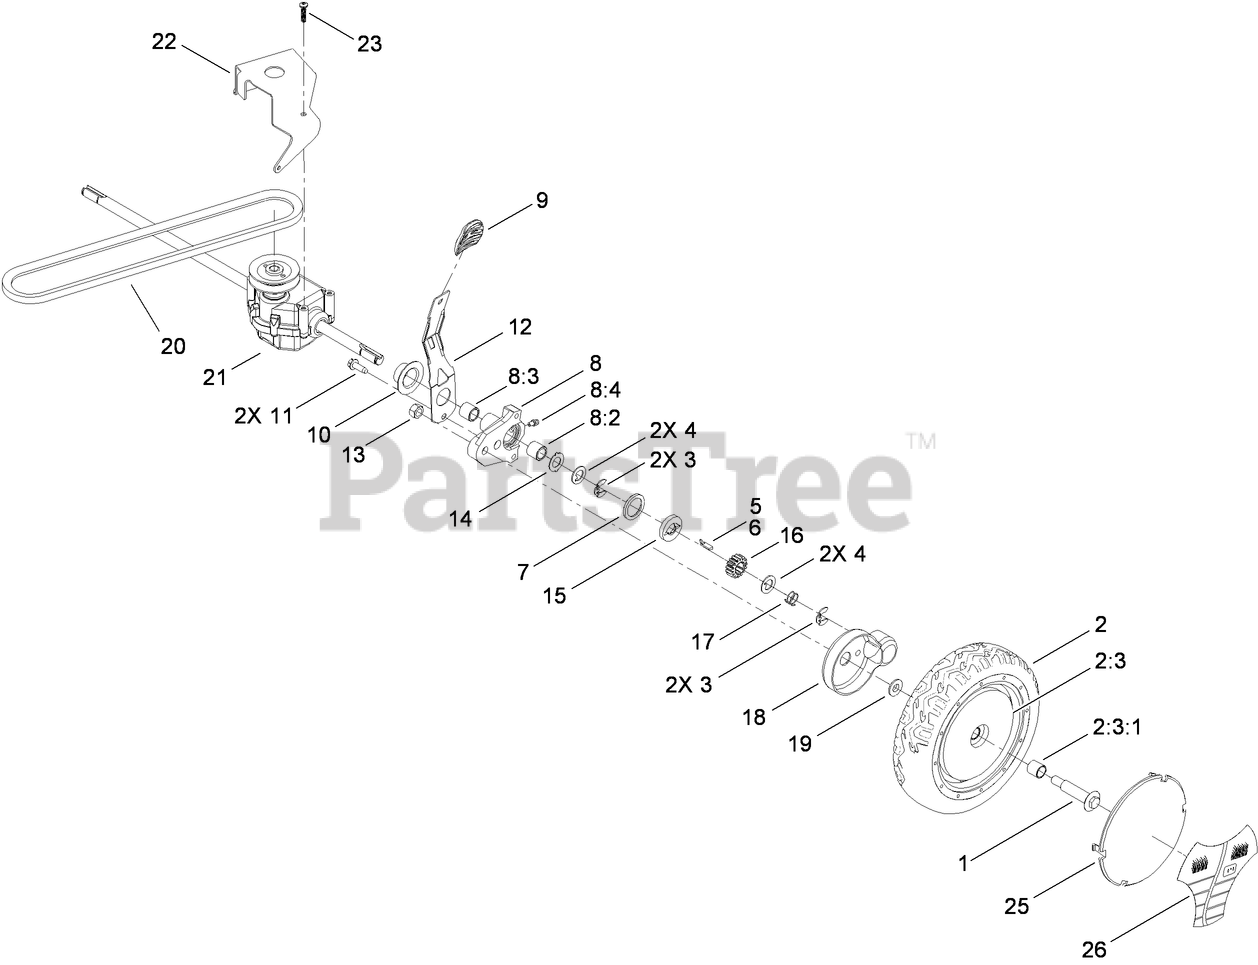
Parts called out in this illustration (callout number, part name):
1	BOLT-SHOULDER
2	8 INCH WHEEL AND GEAR ASM
2:3	Loose Parts Package
2:3:1	BUSHING
3	RING-RETAINING,CLIP
4	WASHER-THRUST, KEYED
6	KEY-ROCKING, LH
7	RING-FRICTION
8	PIVOT ARM ASM
8:2	BUSHING
8:3	BUSHING
8:4	FITTING-GREASE
9	KNOB-LEVER, HOC
10	CAP-END
11	SCREW-HWHTF
12	ARM-SPRING
13	LOCKNUT
14	WASHER-ARM, PIVOT
15	WASHER-CLUTCH
16	GEAR-PINION
17	SPRING-COMPRESSION
18	COVER-WHEEL
19	SPACER-COVER, WHEEL
20	V-BELT
22	BRACKET-TRANSMISSION
23	SCREW-PLASTITE
25	COVER-WHEEL
26	LABEL-WHEEL, SMART
